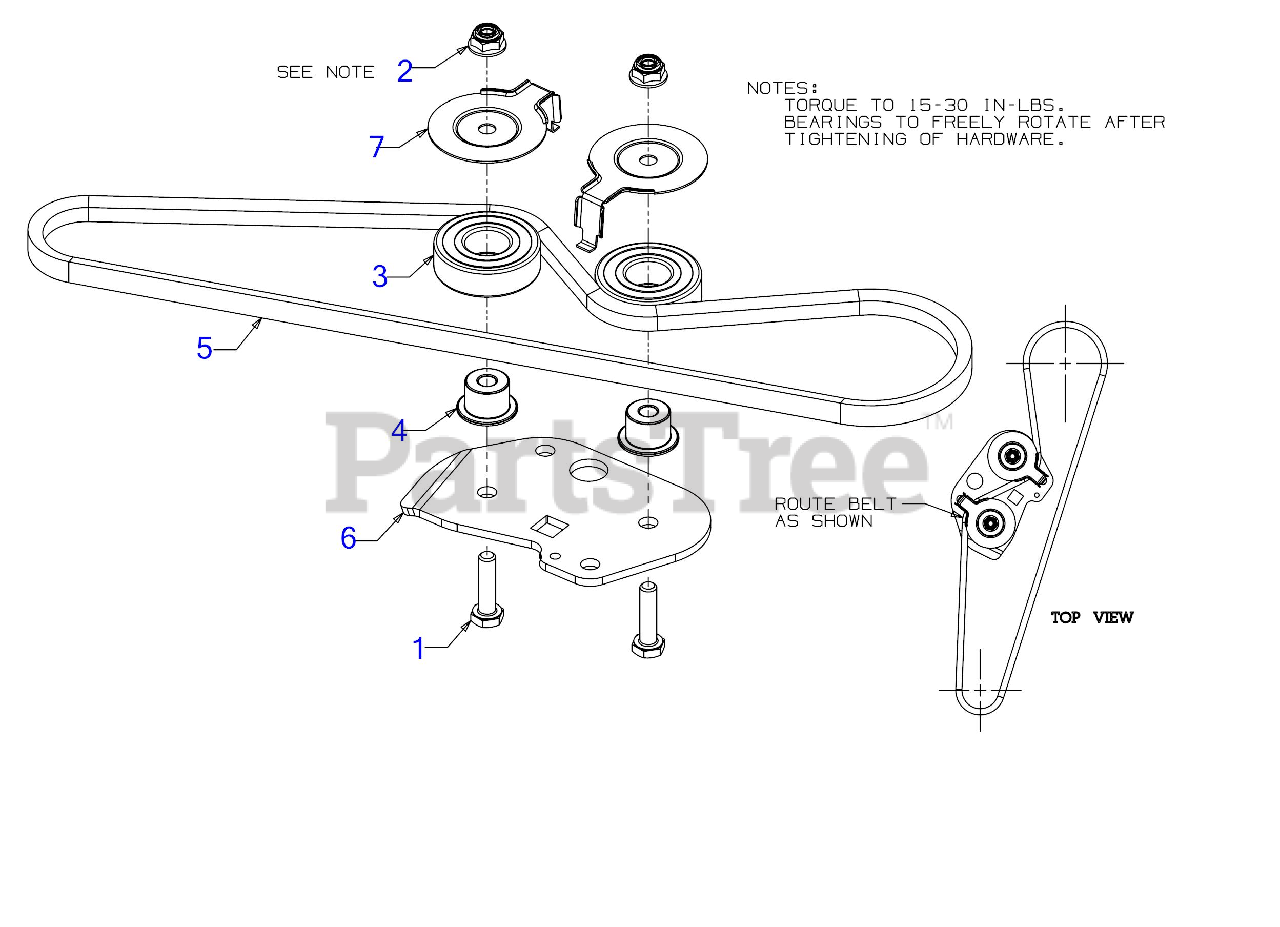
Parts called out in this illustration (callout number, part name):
1	SCREW 1/4-20 X1.00 GR5
2	FLANGE LOCK NUT
3	BALL BEARING
4	FLANGE SPACER
5	BELT 3/8 x 32.2"
6	IDLER BRACKET
7	GUARD BELT
